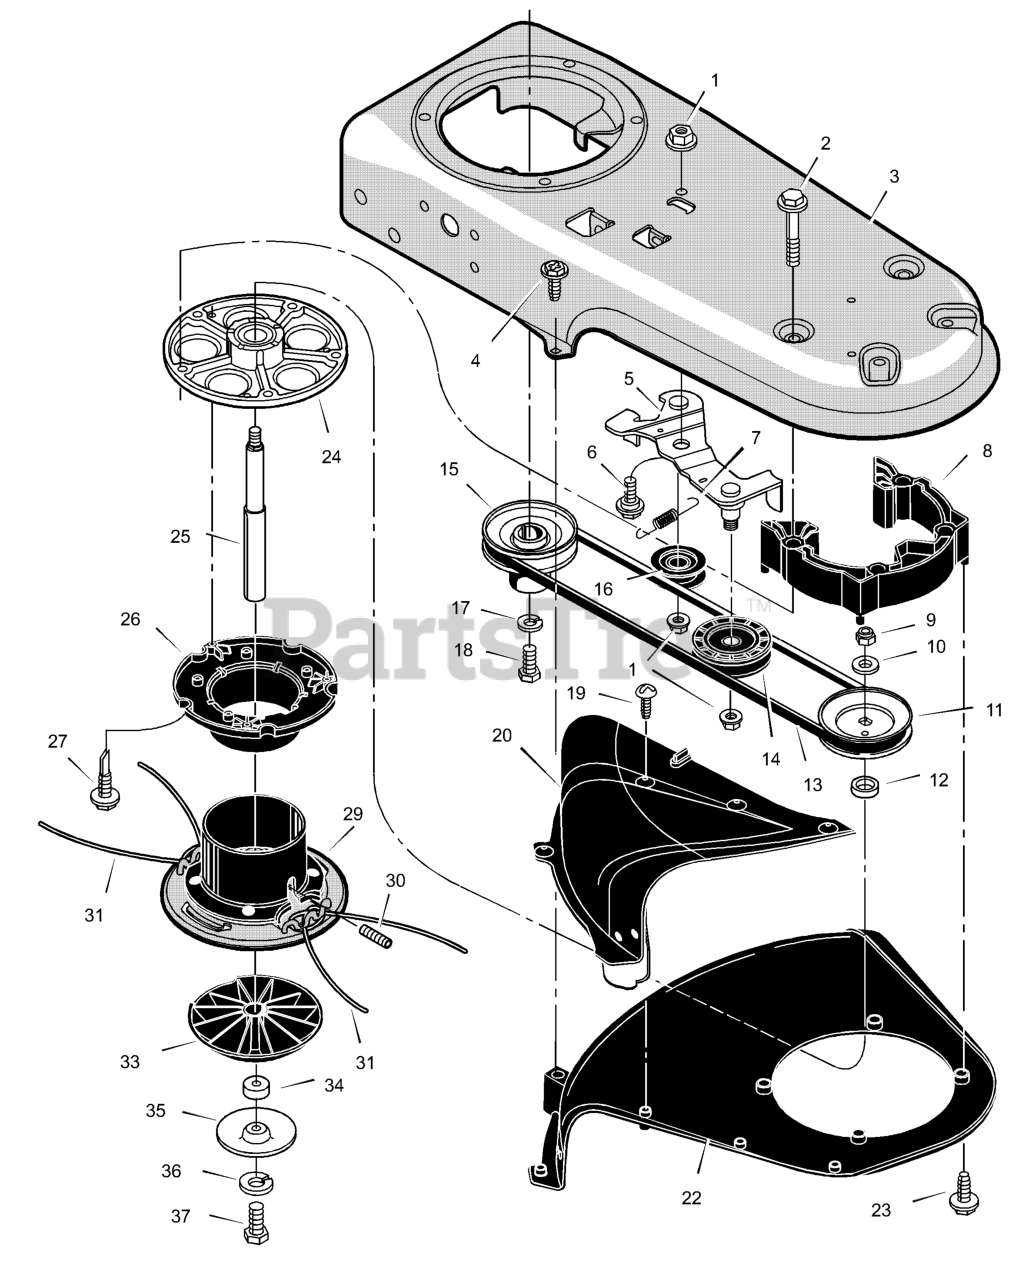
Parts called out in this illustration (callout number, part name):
5	IDLER ASSEMBLY
11	PULLEY, Cutting Head
14	PULLEY, Idler
15	PULLEY, Engine
16	PULLEY, Idler
17	LOCKWASHER
20	GUARD Assembly
24	JACKSHAFT HOUSING ASSEMBLY
25	JACKSHAFT
26	WRAP, Upper Head
29	ASSEMBLY, Cutting Disc
30	SCREW, Set
31	LINE, Cutting
33	GUIDE, Height
35	SHIELD, Abrasion
36	LOCKWASHER
